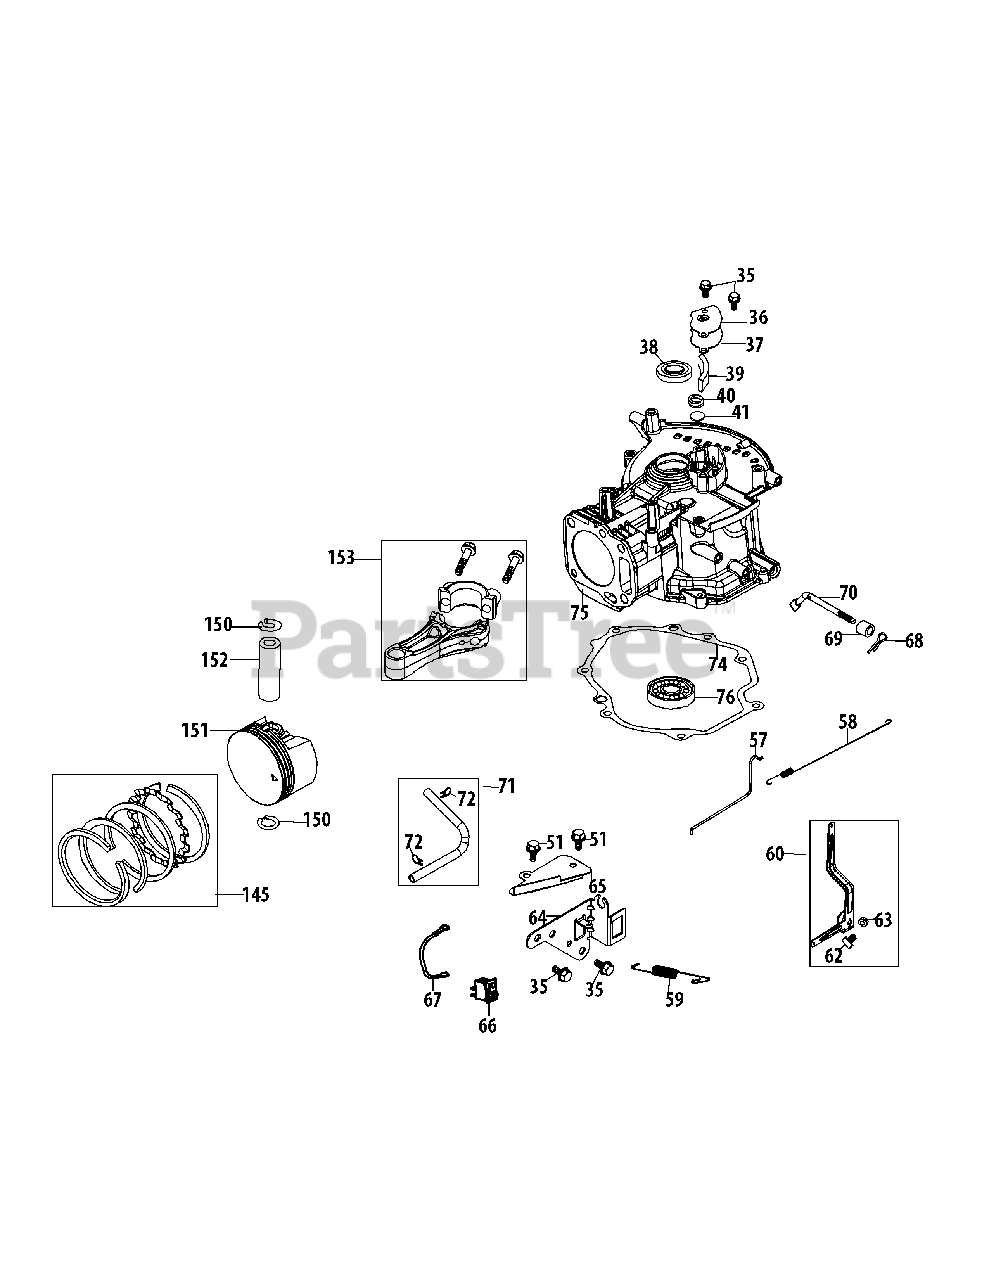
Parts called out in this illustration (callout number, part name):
35	Bolt M6X14 Multi-Purpose
36	Breather Cover Plate
37	Breather Gasket
38	Upper Crankshaft Seal
39	Breather Screen
40	Breather Valve Spring
41	Breather Valve
51	Bolt M6X12 Multi-Purpose
57	Throttle Linkage
58	Throttle Linkage Spring
59	Governor Spring
60	Governor Arm Assembly
62	Governor Arm Bolt
63	Governor Arm Nut M6
64	Component Bracket
65	Air Vane Cover Plate
66	Ignition Switch
67	Ignition Switch Ground Wire
68	Governor Arm Shaft Cotter Pin
69	Governor Seal
70	Governor Arm Shaft
71	Breather Hose Assembly
72	Breather Hose Clamp
74	Crankcase Cover Gasket
75	Crankcase
76	Main Bearing
145	Piston Ring Set
150	Piston Pin Snap Ring
151	Piston
152	Piston Pin
153	Connecting Rod Assembly
